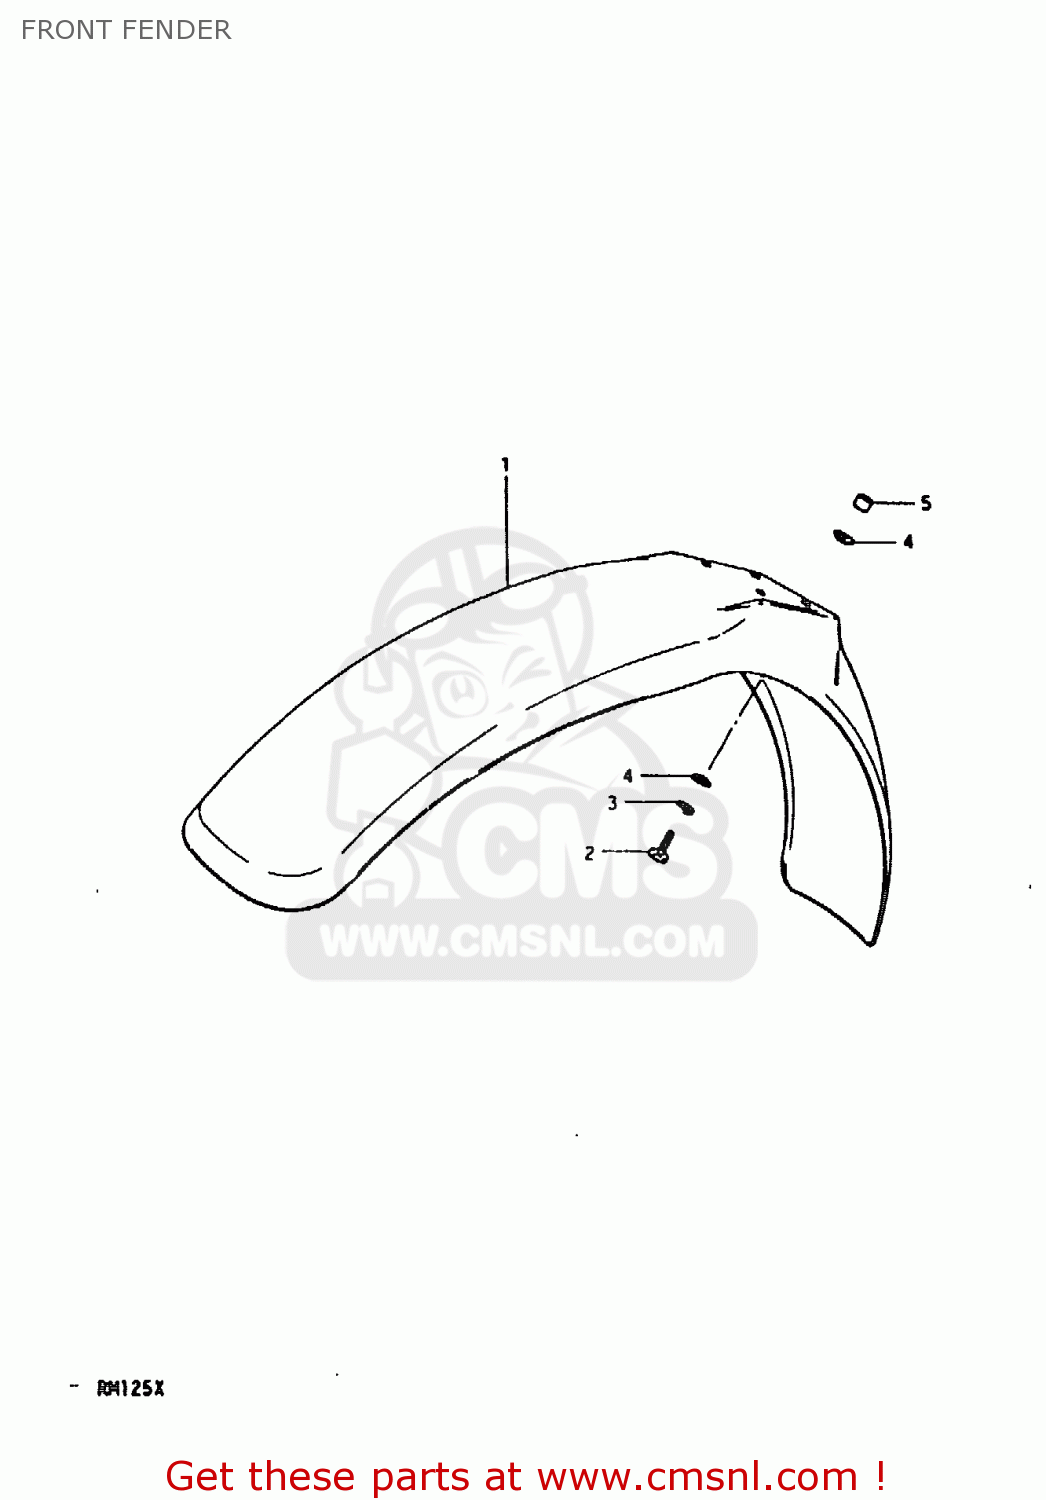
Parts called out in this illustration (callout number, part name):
1	FENDER,FRONT
2	BOLT
3	LOCK WASHER
4	WASHER
5	SPACER,FRONT FENDER
